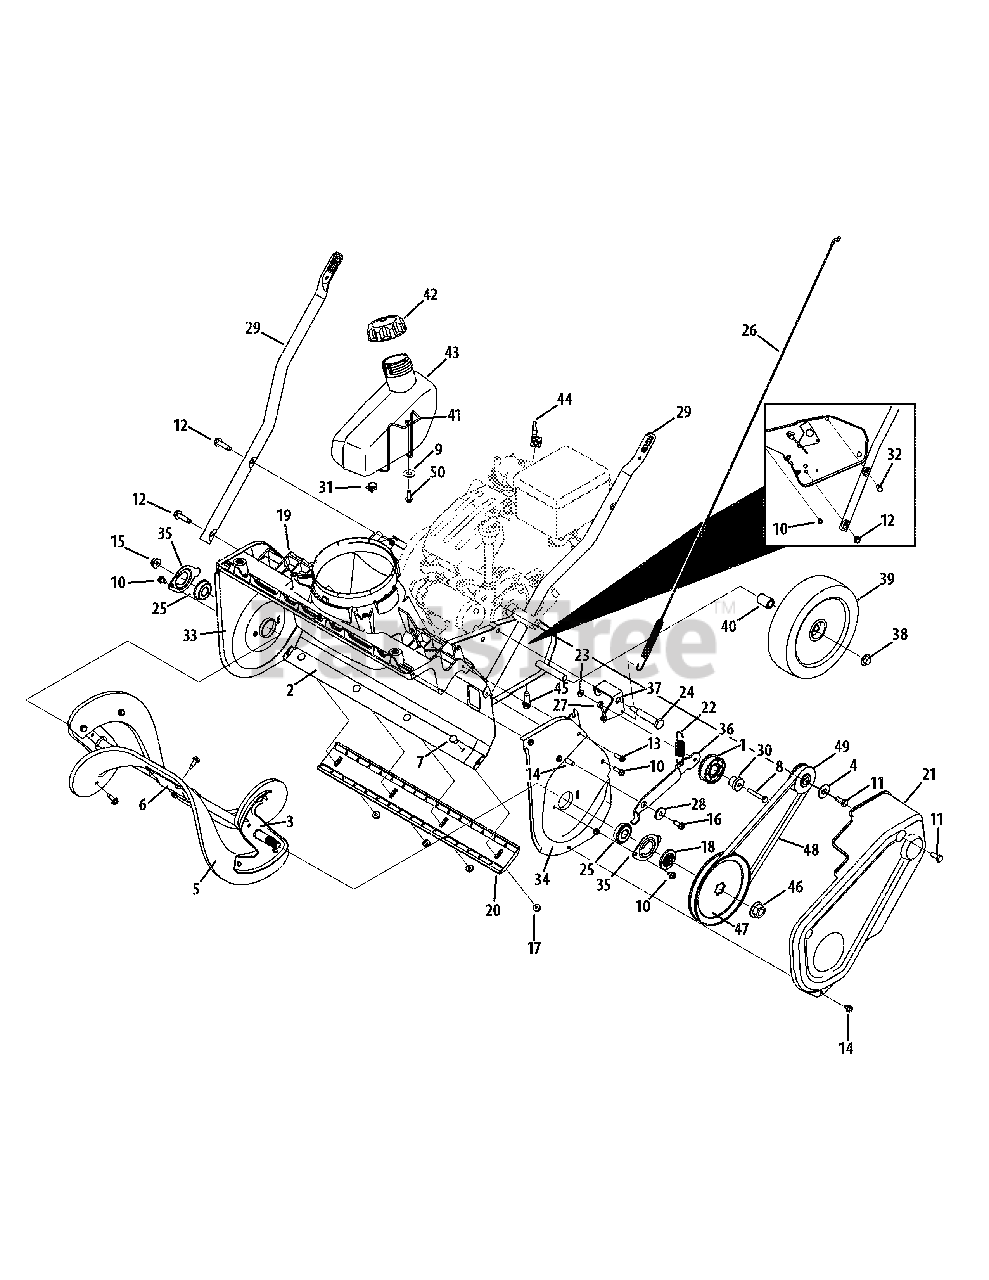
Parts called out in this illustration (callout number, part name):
1	Idler Pulley Assembly
2	Frame
3	Auger Axle Assembly
3	Auger Paddle
4	Flat Washer, .330 x 1.250 x .120
5	Auger Replacement Kit
6	Center Auger Bracket
7	Carriage Screw, 1/4-20 x .62
8	Hex Washer Screw, 1/4-20 x 1.500
9	Flat Washer, .265 x 1.000 x .030
10	Hex Washer Screw, 1/4-20 x .625
11	Hex Lock Screw, 5/16-24 x .750
12	Hex Washer Screw, 5/16-18 x 1.250
13	Hex Washer Screw, 1/4-15 x .750
14	Hex Washer Screw, 1/4-20 x .500
15	Flange Lock Nut, 3/8-16
16	Hex Washer Screw, 5/16-18 x .750
17	Flange Lock Nut, 1/4-20
18	Pulley Hub
19	Chute Adapter
20	Shave Plate
21	Belt Cover
22	Extension Spring, .70 x 3.035
23	Push Nut, .25 x .50
24	Shoulder Bolt, 5/16-24 x .496 x 2.18
25	Ball Bearing
26	Clutch Cable
27	Drive Cable Wire Support
28	Shoulder Spacer
29	Lower Handle
30	Shoulder Spacer, .260 x .785 x .538
31	Hose Clamp, .490
32	Hex Screw, 5/16-24 x 1.25
33	RH Auger Plate
34	LH Auger Plate
35	Bearing Cup
36	Idler Bracket
37	Cable Idler Bracket
38	Push Cap, 1/2
39	Wheel, 8 x 1.7
40	Sleeve Spacer, .525 x .78 x 1.00
41	Gas Tank Wire Support
42	Fuel Cap
43	Fuel Tank, 2 qt.
44	Choke Extension Lever
45	Hex Washer Screw, 3/8-16 x 1.000
46	Flange Nut, 9/16-20
47	Pulley, 1/2 x 6.00
48	Belt, .500 x 35.06
49	Pulley Half, .625 x 2.25
50	Tri-Plask Screw, 1/4-10 x .625
51	Hex Lock Screw, 5/16-24 x .875
